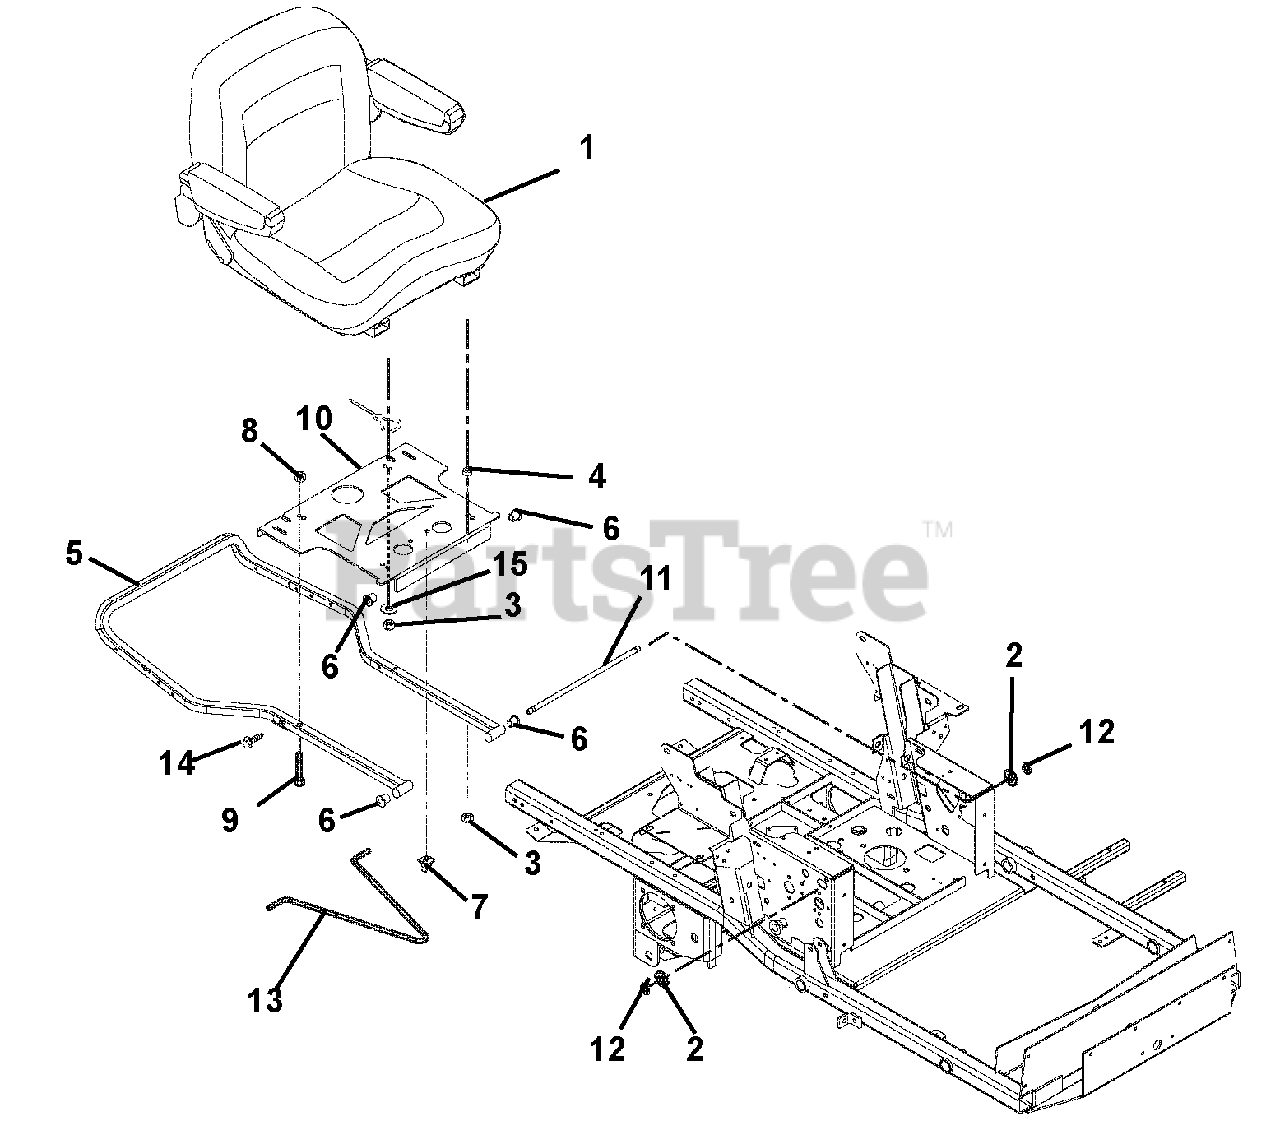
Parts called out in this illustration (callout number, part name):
1	Seat
2	Washer, Flat Steel .531 x 1.06 x .095
3	Nut, Locking Top Flange .31-18
4	Bushing, Sleeve .377 x .624 x .235
5	Weldment, Hood Frame
6	Bushing-Flange .515 x .750 x .745 x 1.00
8	Nut, Locking Top Flange .38-16
9	Bolt, Rib Neck .38-16 x 1.50
10	Weldment, Seat Pivot Plate
11	Rod, Seat Frame Pivot
12	Ring, Retaining External .500 x .050
13	Rod, Prop
14	Screw, Tapping .25-20 x .50 Hex Washer Head
15	Washer, Flat Steel .344 x 1.25 x .135
